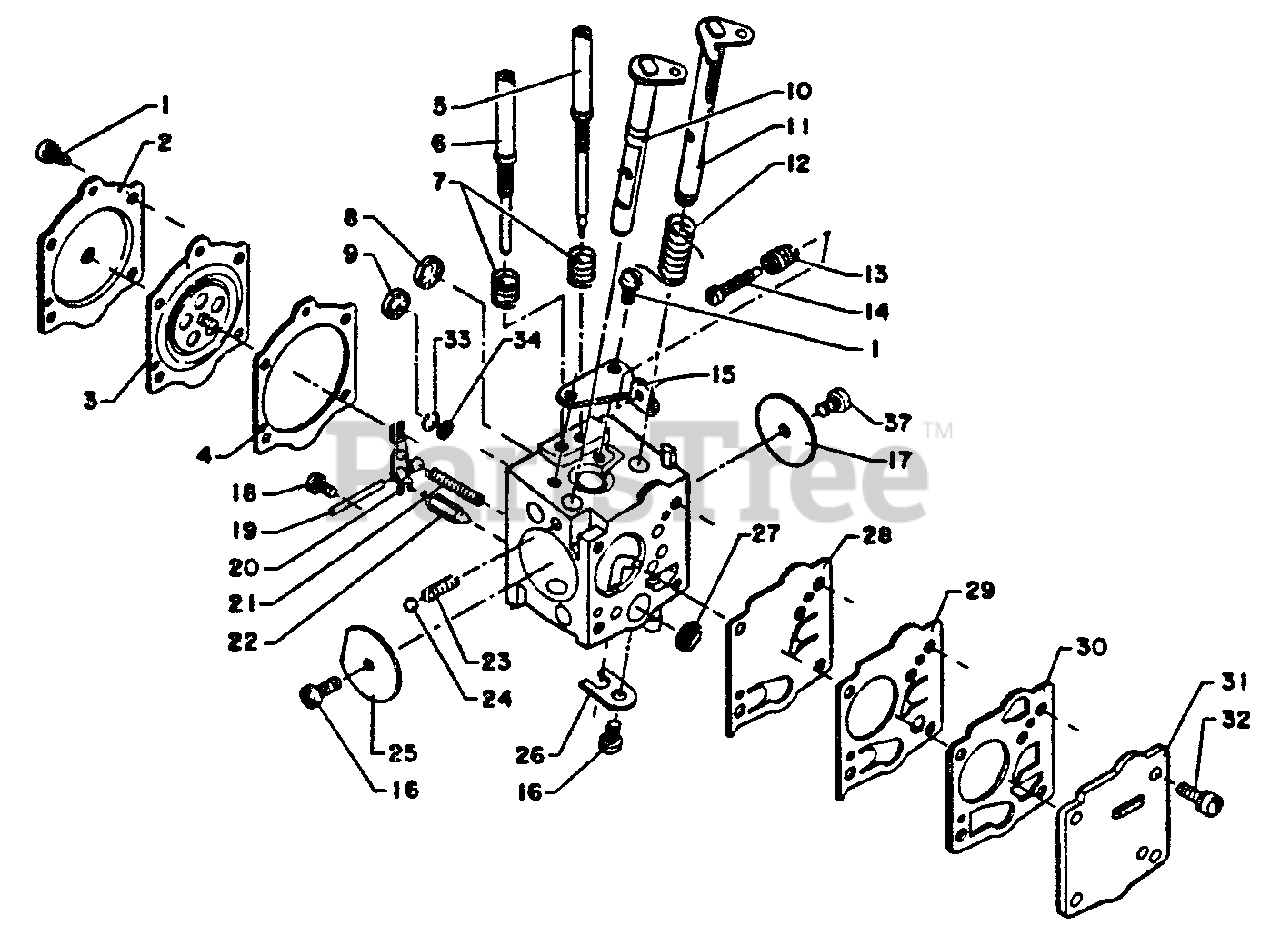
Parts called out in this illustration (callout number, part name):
1	SCREW
2	COVER, DIAPHRAGM
3	DIAPHRAGM
4	GASKET, METERING
5	NEEDLE, LOW SPEED
6	NEEDLE, HIGH SPEED
8	PLUG, WELCH
9	PLUG, WELCH
10	SHAFT, CHOKE
11	SHAFT, THROTTLE
12	SPRING, THROTTLE RETURN
13	SPRING, IDLE ADJUST
14	SCREW, IDLE ADJUST
15	BRACKET, IDLE ADJUST
17	VALVE, THROTTLE
18	SCREW, METERING LEVER PIN
19	PIN, METERING LEVER
20	LEVER, METERING
21	SPRING, METERING LEVER
22	VALVE, NEEDLE
23	SPRING, CHOKE
24	BALL, CHOKE
25	VALVE, CHOKE
26	RING, RETAINING
27	STRAINER
28	DIAPHRAGM, PUMP
29	DIAPHRAGM
31	COVER, PUMP
32	SCREW
33	RING, RETAINING
34	STRAINER
37	SCREW ASSY
